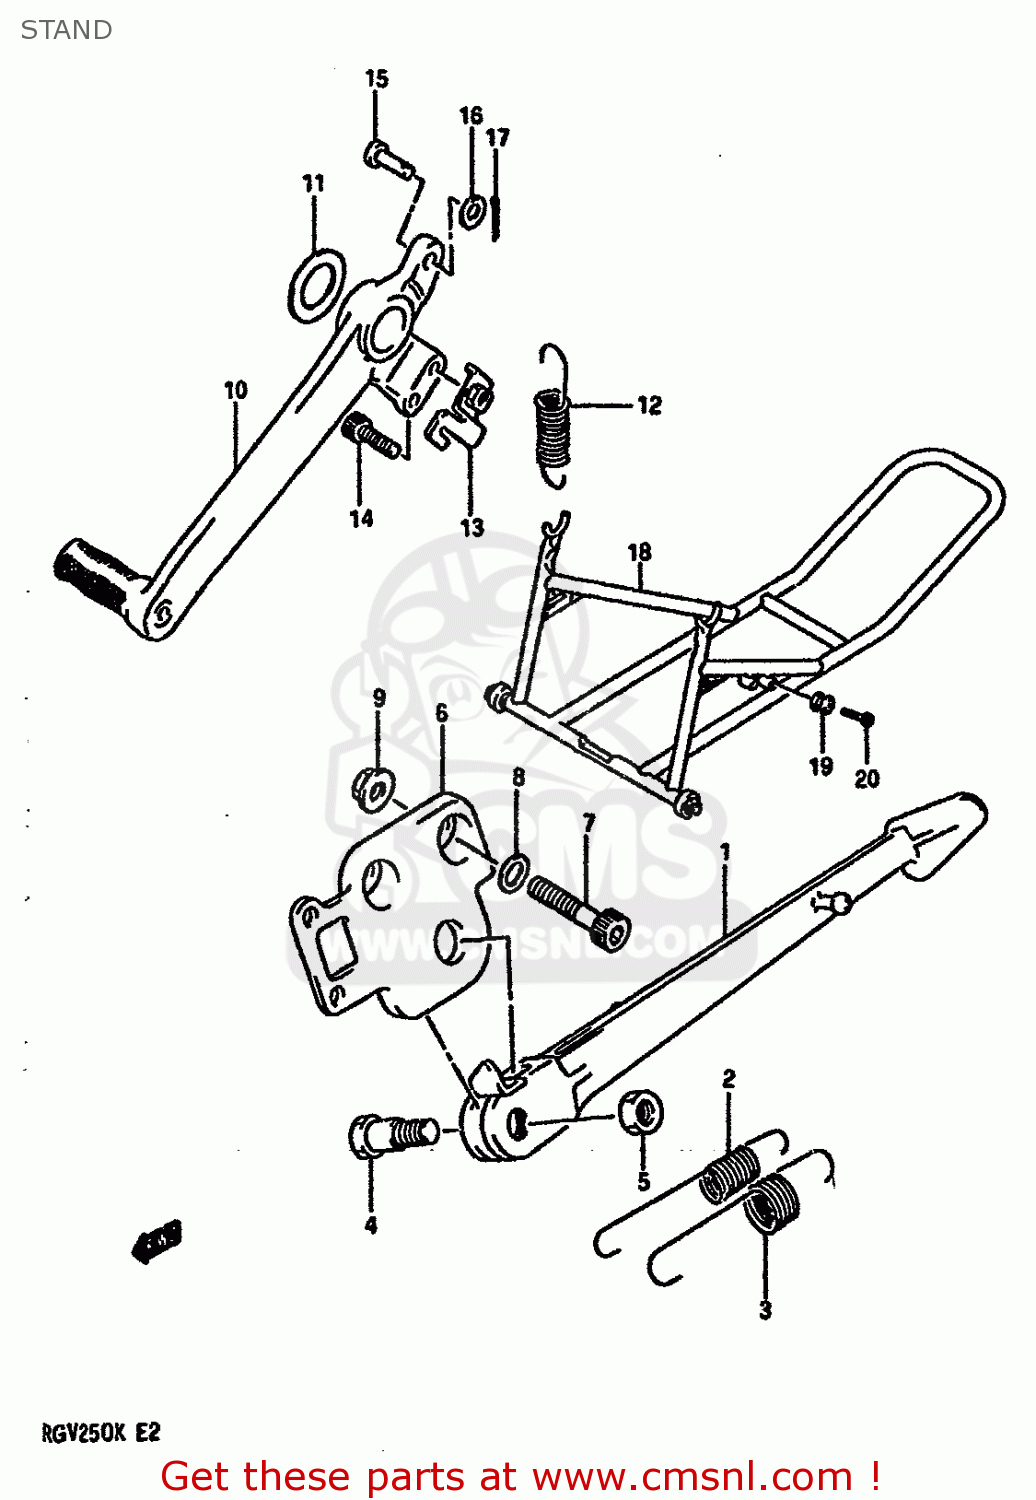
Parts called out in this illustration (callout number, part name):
1	STAND,PROP
2	SPRING
3	SPRING
4	BOLT L:30
5	NUT
6	BRACKET,PROP STAND
7	BOLT (8X35)
8	WASHER
9	NUT
10	PEDAL,BRAKE
11	WASHER(18.2X27X1)
12	SPRING
13	BRACKET,STOP LAMP SWITCH SPR
14	BOLT
15	PIN
16	WASHER
17	PIN
18	STAND ASSY,RR
19	HOLDER,STAND
20	BOLT, REAR (8X30)
